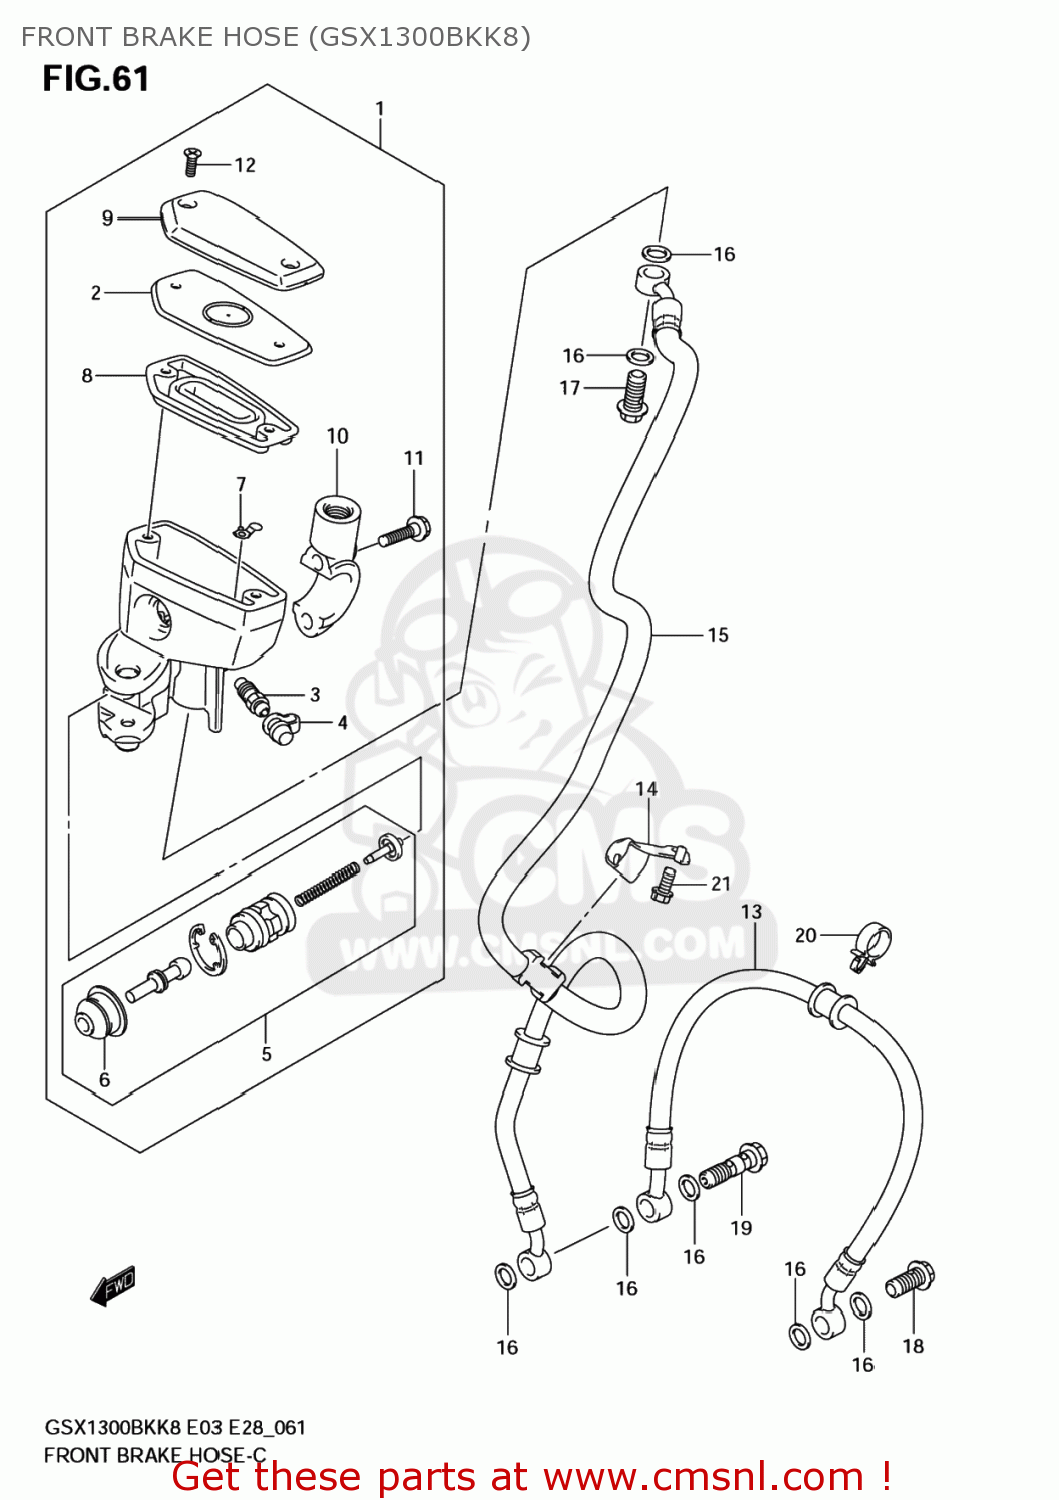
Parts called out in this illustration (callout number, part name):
1	CYLINDER ASSY,FR MASTER
2	PLATE
3	BLEEDER
4	CAP,BLEEDER
5	PISTON / CUP S
6	BOOT
7	PROTECTOR
8	DIAPHRAGM,R
9	CAP
10	HOLDER
11	BOLT(6X22)
12	SCREW
13	HOSE,FR BRAKE NO.2
14	CLAMP,FR BRAKE HOSE NO.1
15	HOSE,FR BRAKE NO.1
16	WASHER(10X15X1.5)
17	BOLT UNION
18	BOLT UNION
19	BOLT UNION
20	CLAMP
21	BOLT
